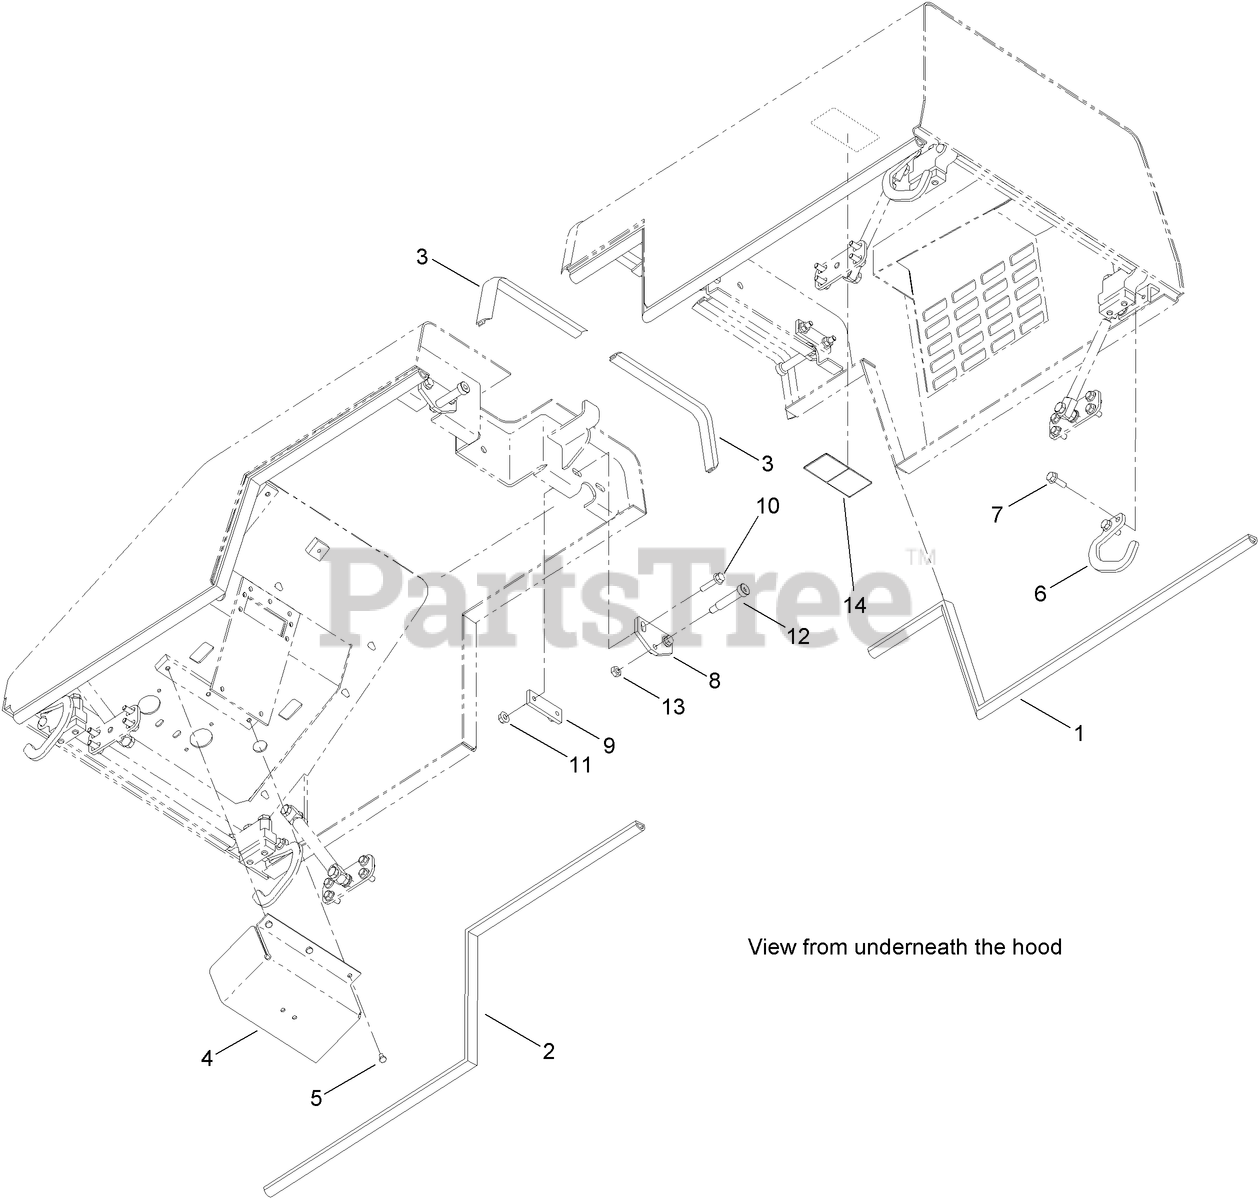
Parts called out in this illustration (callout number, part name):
1	STRIP-WEAR
2	STRIP-WEAR
3	GASKET-GRIPPING, SELF
4	COVER-SWITCH, CONTROL
5	SCREW-HH
6	BRACKET-HOOD, STOP
7	SCREW-HHF
8	PLATE
9	PLATE-BACKING, LOCK
10	SCREW-HHF
11	NUT-HF
12	SCREW-HSBH, SHOULDER
13	NUT-HEX
14	DECAL-SURFACE, HOT
